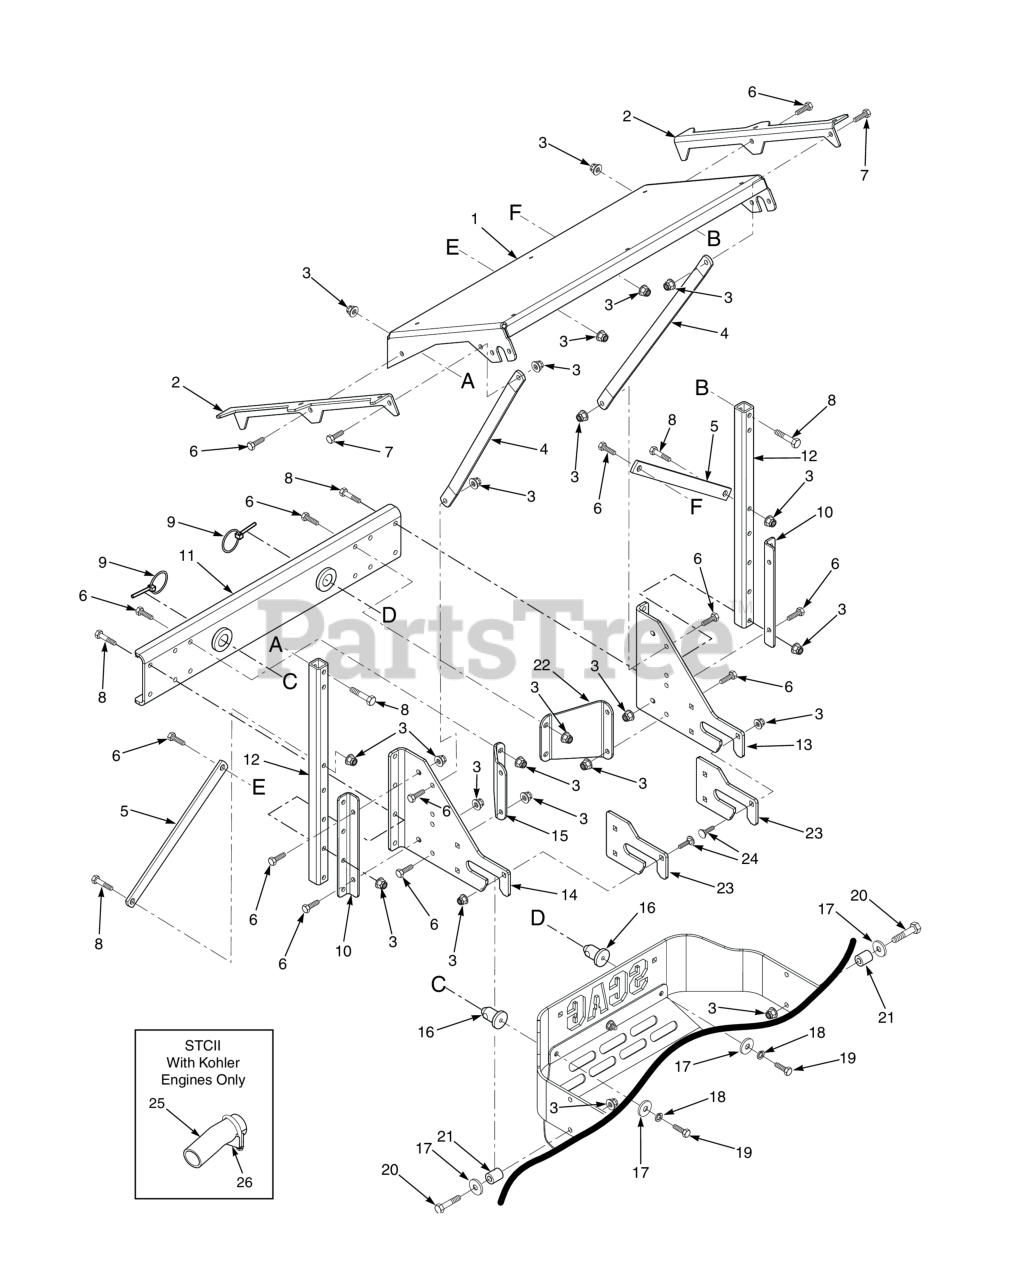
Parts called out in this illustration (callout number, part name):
1	Support Frame, Hopper
2	Bracket, Hopper Support
3	Nut, Flange Elastic Stop Nut, 3/8-16
4	Brace, Stiffener
5	Brace, Engine Mounting
6	Bolt, Hex Head, 3/8-16 x 1 Gr. 5
7	Bolt, Hex Head 3/8-16 x 1-1/4" Grade 8
8	Bolt, Hex Head 3/8-16 x 2-1/4" - 61"
9	Quick Pin, 5/16" Dia.
10	Mounting Bracket, Tube
11	Mounting Bracket Weldment
12	Tube, Upright
13	Mounting Bracket, GC R.H.
14	Mounting Bracket, GC L.H.
15	Angle Bracket, GC
16	Pin, GC Locator
17	Flatwasher, 3/8-.406 x 1-1-1/2 x 7 Gauge
18	Lockwasher, 3/8" Spring, Kawasaki FX / FT & FT-EFI / B&S 32BV
19	Bolt, Hex Head 3/8-16 x 1-1/4" Grade 8
20	Bolt, Hex Head 3/8-16 x 2-1/4" - 61"
21	Spacer
22	Angle Bracket, GC
23	Wear Plate, GC
24	Carriage Bolt, 3/8-16 x 1-1/4"
25	TUBE, EXHAUST
26	Clamp, Muffler (Clamp Only)
